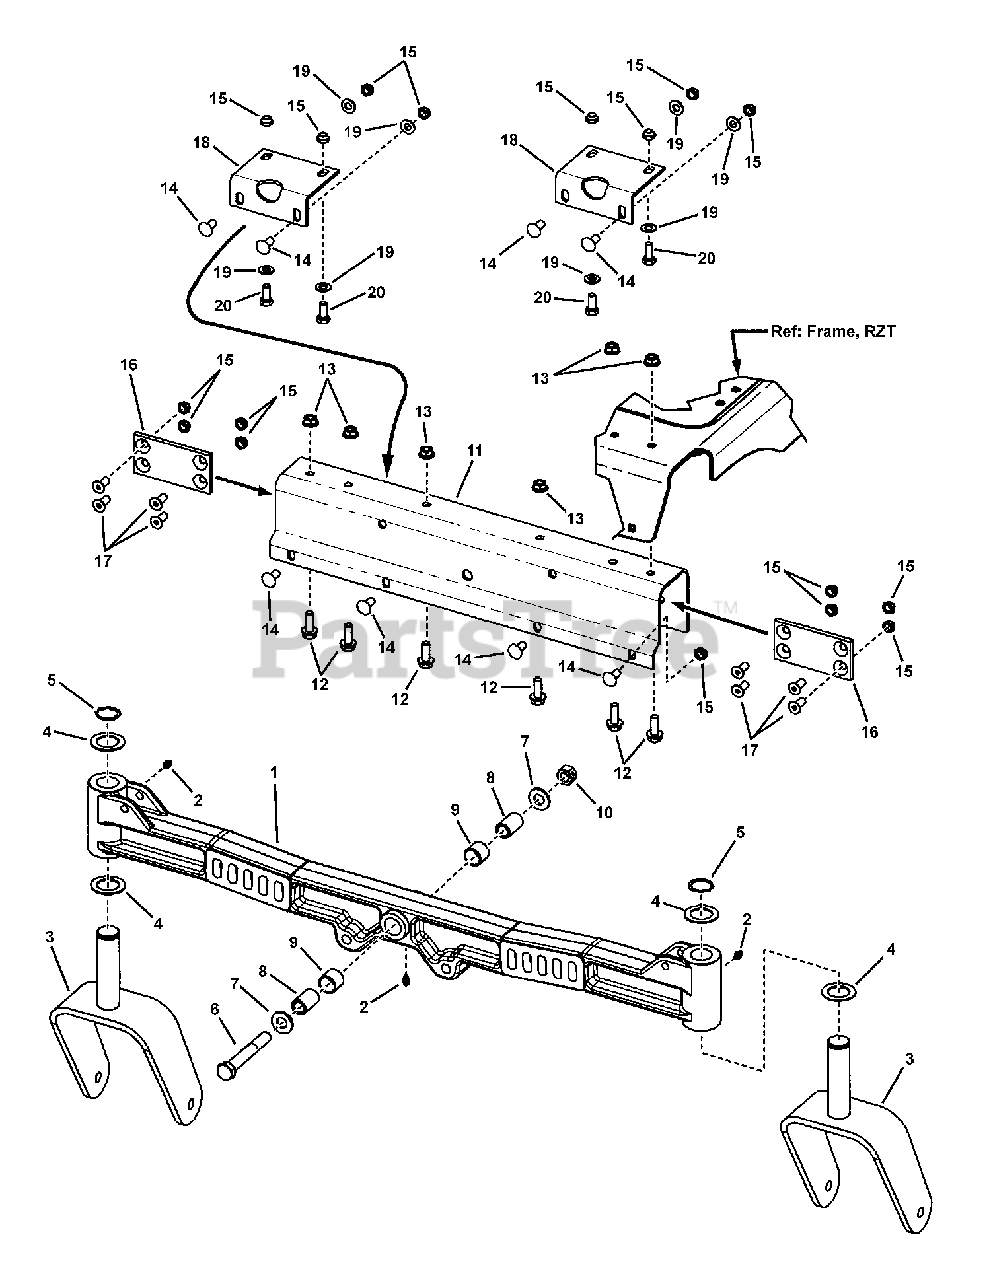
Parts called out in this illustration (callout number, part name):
1	FRONT AXLE, Cast (Cardinal Red)
2	LUBE FITTING, 3/16" Press-In
3	WELDMENT, Caster (Cardinal Red)
4	THRUST WASHER, 1" I.D.
5	RETAINING RING, 1" External
6	SCREW, 1/2-13 x 3-1/2" Hex Head Cap, YZ
7	WASHER, 1/2" SAE Flat
8	SPACER, Axle Pivot
9	BEARING SLEEVE
10	NUT, 1/2-13 Hex Center Lock, GR 5, YZ
11	BRACKET, Axle (Cardinal Red)
12	BOLT, 5/16-18 x 7/8" Hex Flange Lock
13	NUT, 5/16-18 Hex Flange Lock, GR 5
14	BOLT, 5/16-18 x 3/4" Short Neck Carriage, GR 5
15	NUT, 5/16-18 Hex Top Lock, GR B
16	PLATE, Friction
17	SCREW, 5/16-18 x 1" Flat Head Countersunk
18	BRACKET, Axle Support
19	WASHER, .34 x .69 x .08 Flat
20	SCREW, 5/16-18 x 3/4" Hex Head Cap, GR 5, YZ
